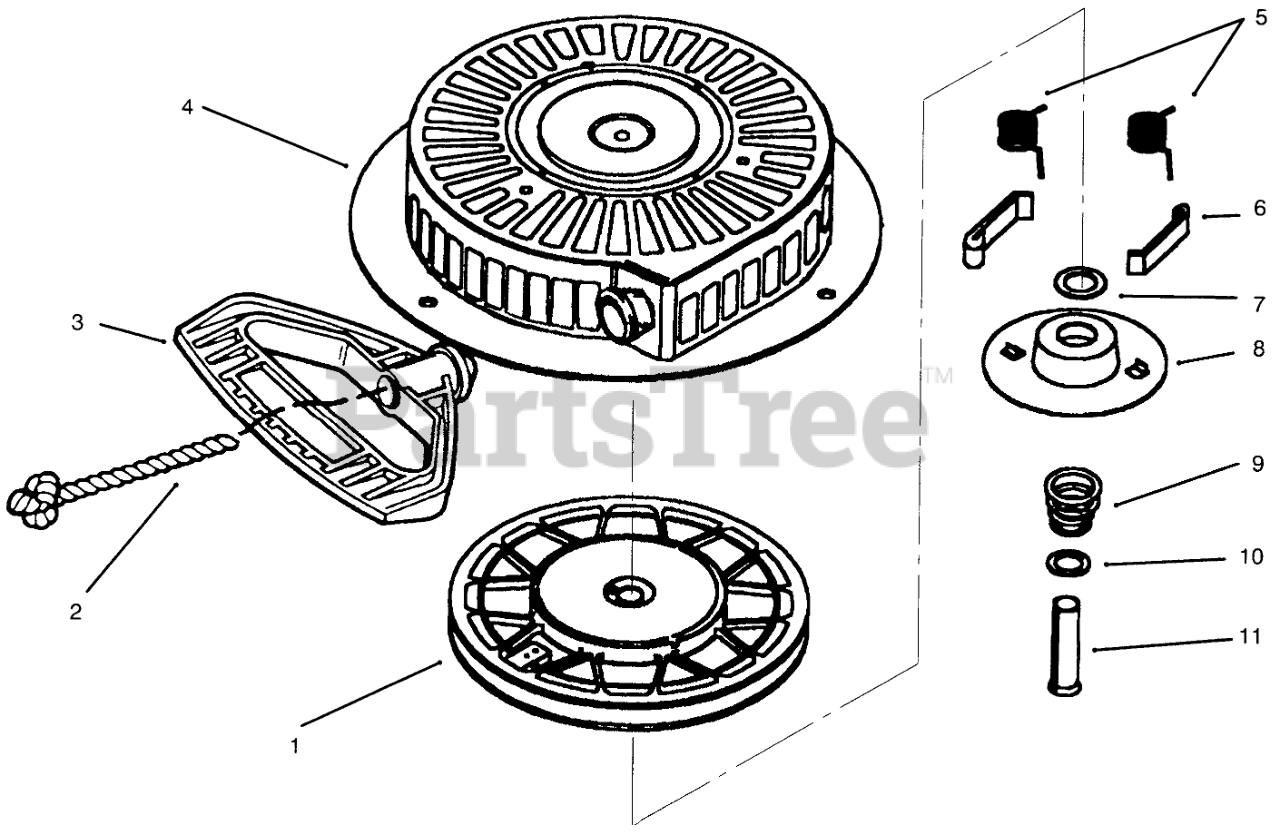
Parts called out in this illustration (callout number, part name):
1	Pulley and Rewind Spring ASM
2	Rope-Starter (98 cut to length)
3	Handle-Starter, Mitten Grip
4	Spring, Pawl
5	Spring-Dog
6	Dog-Starter
8	Retainer
9	Spring-Brake
11	Pin-Spring (Incl. Ref. #7)
